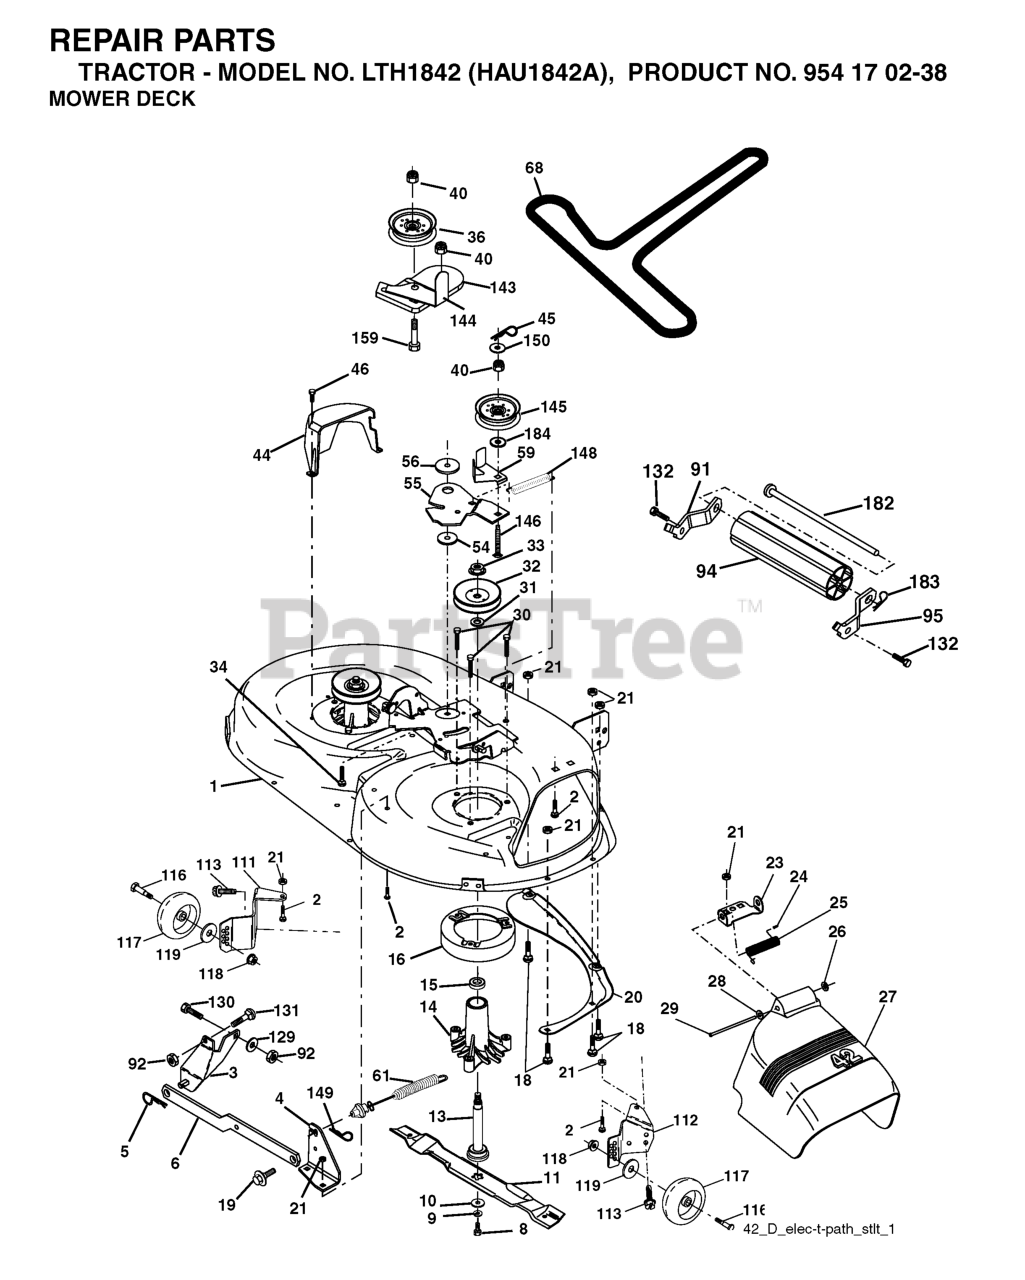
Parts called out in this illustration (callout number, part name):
1	42" DECK KIT
2	RP BOLT 5/16-18 X3/4 ZN/YEL GR
3	BRKT ASM SWAY BAR
4	BRACKET SWAY BAR 42" DECK
5	RETAINER-SPRNG RB
6	BAR SWAY DECK
8	BLADE BOLT
9	LOCKWASHER
10	WASHER.BLADE
11	42" HI-LIFT BLADE
13	SHAFT ASM VENT
14	HOUSING.MANDREL.VENTED (MACHD)
16	STRIPPER.MANDREL.ROUND.BLACK
18	BOLT
19	BOLT SHD 5/16-18
20	BAFFLE.VORTEX
21	LOCKNUT
23	BRKT, DEFL. MOWER
24	CAP-SLEEVE LT
25	SPRING TORSION
26	NUT PUSH M
27	SHIELD DEFLECTOR
28	Washer 11/32 x 5/8 x 16 Ga SD
29	ROD.HINGE
30	SCREW, WASHER HEAD
31	WASHER.SPACER.MANDREL
32	PULLEY/MANDREL
33	NUT, FLG TOPLOCK 9/16"
34	BOLT.3/8-16X1.50
36	FLAT IDLER PULLEY
40	NUT LOCK FLG 3/8-16 UNC
44	GUARD MANDREL LH BLACK
45	RETAINER M
46	SCREW.1/4-20X5/8
55	ARM IDLER 42" MOWER LT/YT
56	SPACER.RETAINER.MOWER
59	GUARD, BELT
61	SPRING EXT ELEC CLUTCH
68	V-BELT PRIMARY 42"
91	BRACKET ASM NOSEROLLER LH
92	NUT
94	NOSE ROLLER
95	BRACKET ASM NOSEROLLER RH
111	BRACKET, WHEEL
112	BRACKET, WHEEL
113	BOLT.5/16HEX.WHS.HD
116	BOLT M
117	WHEEL.GAUGE.STANDARD
118	LOCKNUT
119	WASHER.5/16.FLAT.STE.STD.
129	WASHER
130	BOLT
131	BOLT D
132	SCREW, 3/8-16X3/4
143	BRACKET, ARM IDLER
144	DNO KEEPER.BELT.42".CLUTCH.CBL
145	PULLEY
146	BOLT, CARRIAGE IDLER BLACK
148	IDLER RETURN SPRING
149	SPRING.RETAINER.YELLOW.ZINC
150	WASHER LT
159	BOLT
182	ROD ROLLER NOSE STANDARD
183	SPRING RETAINER
184	WASHER
